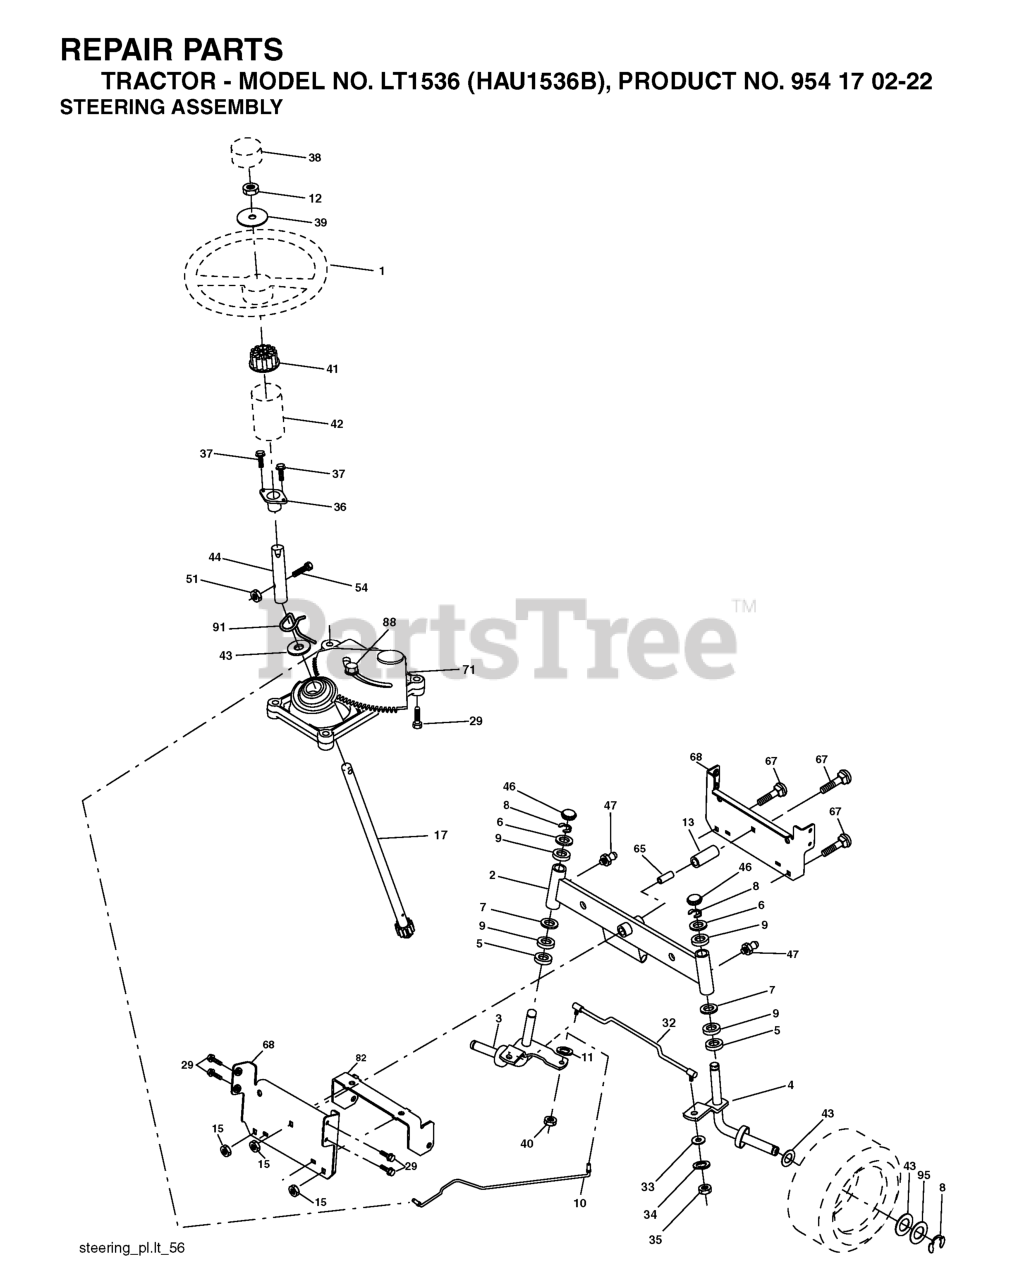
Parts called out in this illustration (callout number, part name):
1	STEERING WHEEL
2	AXLE ASM.
3	SPINDLE.ASM.LH.15"TIRES
4	SPINDLE.ASM.RH.15"TIRES
5	THRUST WASHER
9	BRNG T
10	DRAGLINK.15".TIRES.2001
11	WASHER, LOCK 3/8
12	NUT.HEX.1/2-20
13	TUBE, PIVOT AXLE
15	NUT
17	SHAFT ASM, STEERING
29	SCREW, 3/8-16X3/4
33	WASHER M
34	WASHER.LOCK.HVY.HLCL.SPR.5/16
35	NUT, CROWNLOCK
36	BUSHING, STEERING
37	SCREW.TT.#10-32X.5.3/8.FLANGE
38	CAP.WHEEL.STEERING.GREY
39	Washer 9/16 ID x 1 1/2 OD 11 Ga. Zin
40	NUT CROWNLOCK 3/8-24
41	STEERING WHEEL ADAPTOR
42	BOOT STEERING
44	EXT, STEERING SHAFT
46	CAP.SPINDLE.BLACK
47	FITTING.GREASE.TAPERED
51	NUT.CROWNLOCK.1/4-28
54	Bolt Hex 1/4-28 unf x 1-1/4 Gr. 8
65	SPACER BRACE AXLE
67	BOLT CARRIAGE
68	BRACE.AXLE.15"TIRES
71	STEERING ASM
82	BRACKET
88	BOLT, SHOULDER 7/16-20
91	CLIP.STEERING
95	WASHER.HARDENED
